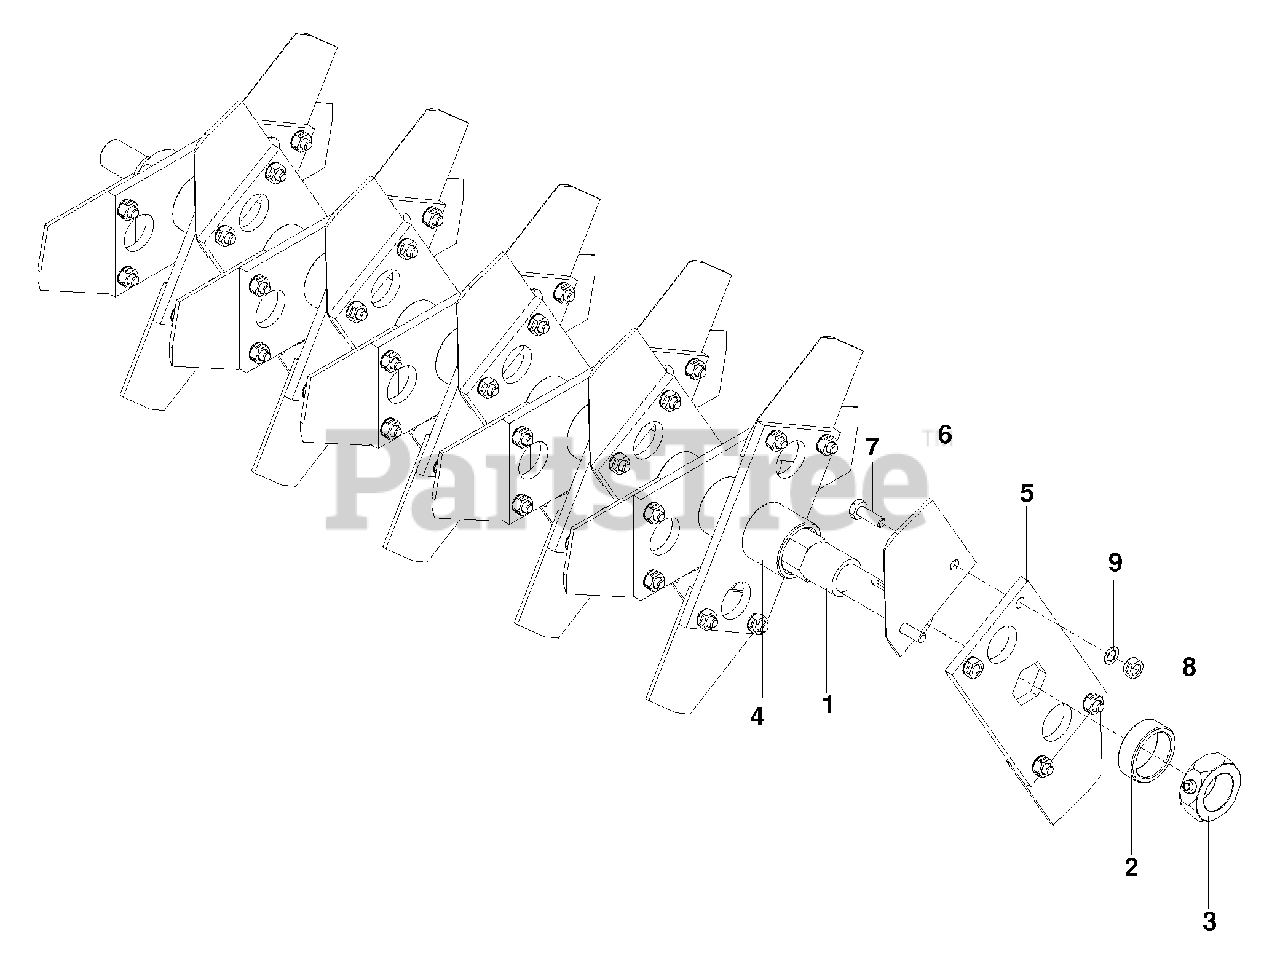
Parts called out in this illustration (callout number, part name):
2	END SPACER
3	JAM NUT w/ SET SCREW
4	SPACER-LONG 22"
5	BLADE PLATE 22"
6	DELTA BLADE 22"
7	HCS 1/4-20 x 3/4 GR8 22"
8	NUT 1/4-20 CTRLK 22"
9	WASHER 1/4 LK 22"
